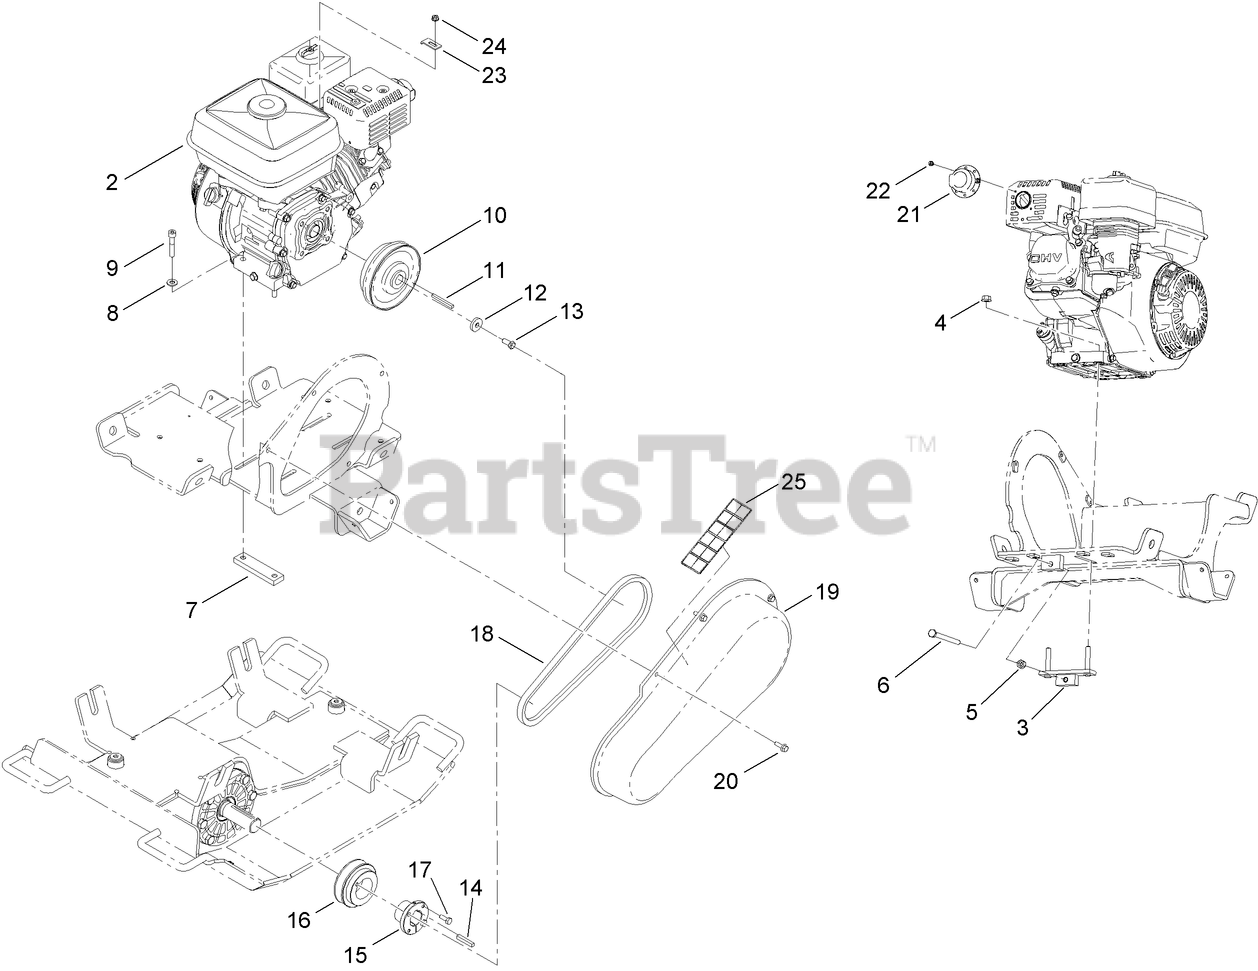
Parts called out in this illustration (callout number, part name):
2	ENGINE-HONDA, GX160
3	BRACKET-ADJUSTER, ENGINE
4	NUT-HF
5	NUT-HEX
6	SCREW
7	PLATE-NUT, ENGINE
8	WASHER-PLAIN
9	SCREW-HSH
10	CLUTCH, S-PLATE
11	KEY-SQUARE
12	WASHER
13	SCREW-HH
14	KEY-SQUARE
15	BUSHING
16	SHEAVE-ECCENTRIC
17	SCREW-HH
18	BELT-V
19	GUARD-BELT
20	SCREW-HHF
21	DEFLECTOR-EXHAUST
22	SCREW-HWH
23	CLIP-THROTTLE
24	NUT-LOCK, FLANGE
25	DECAL-WARNING, PLATE
